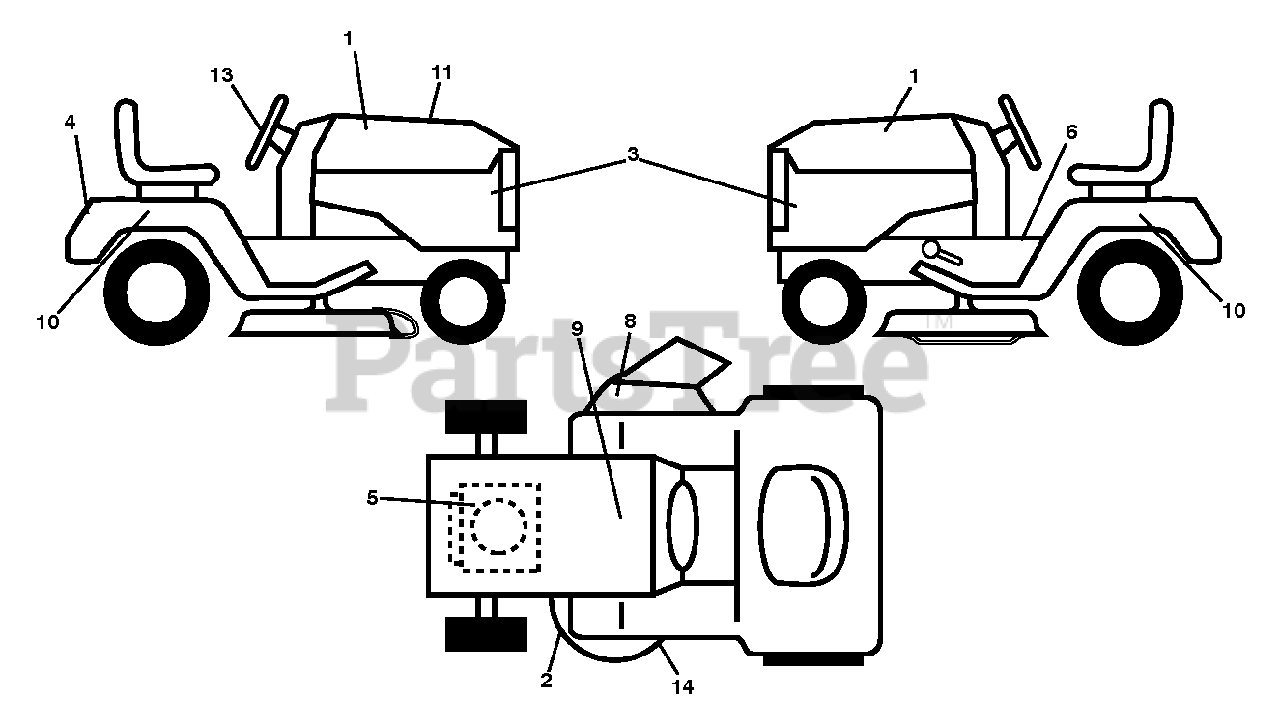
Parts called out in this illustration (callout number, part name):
1	DECAL.HOOD.POULAN.PRO.SET
2	DECAL.MOWER.CAUTION.TENSION.AR
4	DECAL.REAR.FNDR.LOGO.POULAN.PR
5	Decal, Engine BS 22INTK DOM 381708
6	DECAL.WARNING.2007.ENG/FR
8	DECAL.MOWER.WARN.KEEP.HAND.AWY
9	DECAL BTRY SYMBOLS
11	DECAL DECAL.RPL.BSM44.INTK.TLW
13	DECAL.STEER.WHEEL.POULAN.PRO
14	DECAL.MOWER.SCH.48/54.PREM
